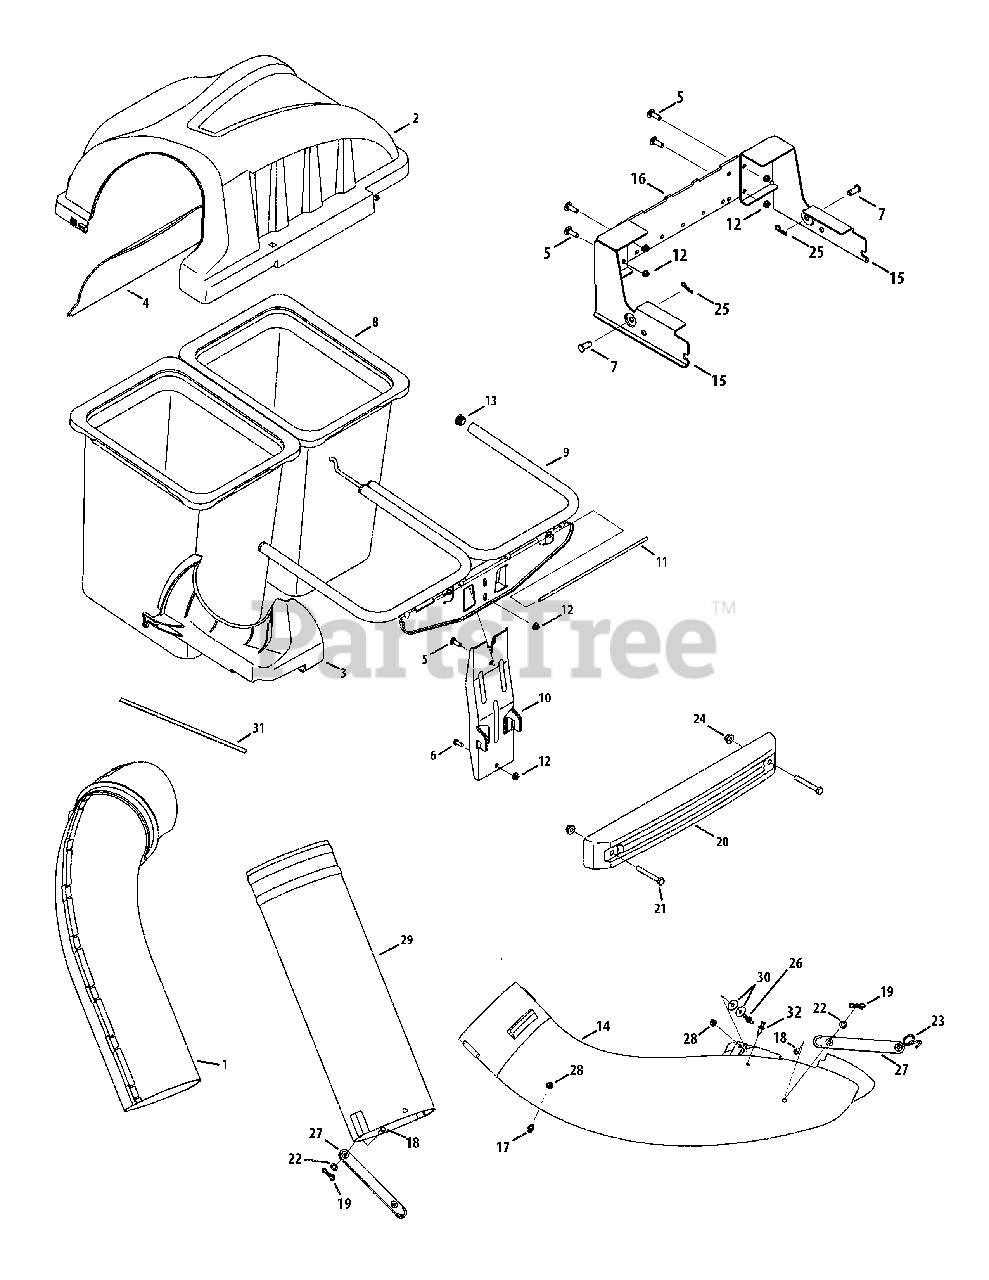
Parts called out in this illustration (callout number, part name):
1	Upper Chute Assembly
2	Twin Bagger Cover Assembly
3	Upper Chute Support
4	Bagger Cover Screen
5	Carriage Screw, 5/16-18 x 1.00"
6	SCREW 5/16-18 x .75 GR5
7	Clevis Pin, .50" Dia. x .78
7	Clevis Pin, .50" Dia. x 1.18
8	Grass-bag Assembly
9	Twin Bag Support Assembly
10	Vertical Support Bracket
11	Cover Hinge Pin
12	Flange Lock Nut, 5/16-18
14	Discharge Chute Elbow
15	RZT Hitch Bracket Kit
17	Grass-catcher Pin
18	Clevis Pin 5/16 x 3/4
19	Bow-Tie Cotter Pin
20	Bagger Weight
21	Hex Head Screw, 3/8 - 16 x 2.75
22	Flat Washer, .344 x .62 x .033
23	Torsion Spring Hook
24	Flange Lock Nut, 3/8 - 16
25	Cotter Pin, .080 x 1.5625 Internal
26	Grass-catcher Pin
27	Chute Strap
28	Flange Lock Nut, 1/4-20
29	Bagger Chute Adapter, 7 In.
30	Flat Washer
31	Foam Strip
32	Shoulder Screw, 5/16-18 x .54
32	Plastic Rivet
